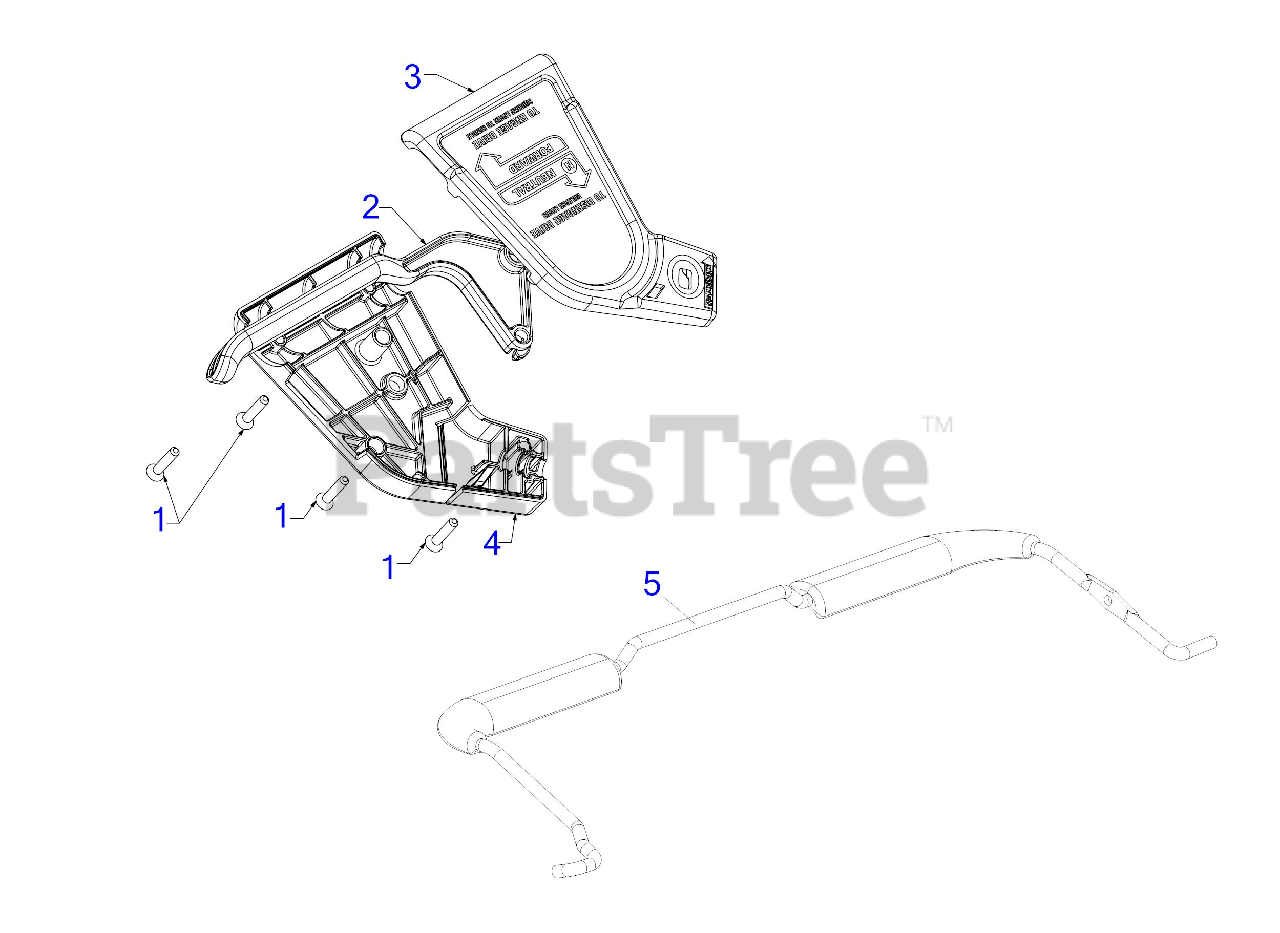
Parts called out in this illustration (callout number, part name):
1	SCREW #10-16 x 1.00
2	ENGAGEMENT LEVER
4	SQUEEZEBOX CONTROL COVER
5	OPERATOR BAIL ASSEMBLY
